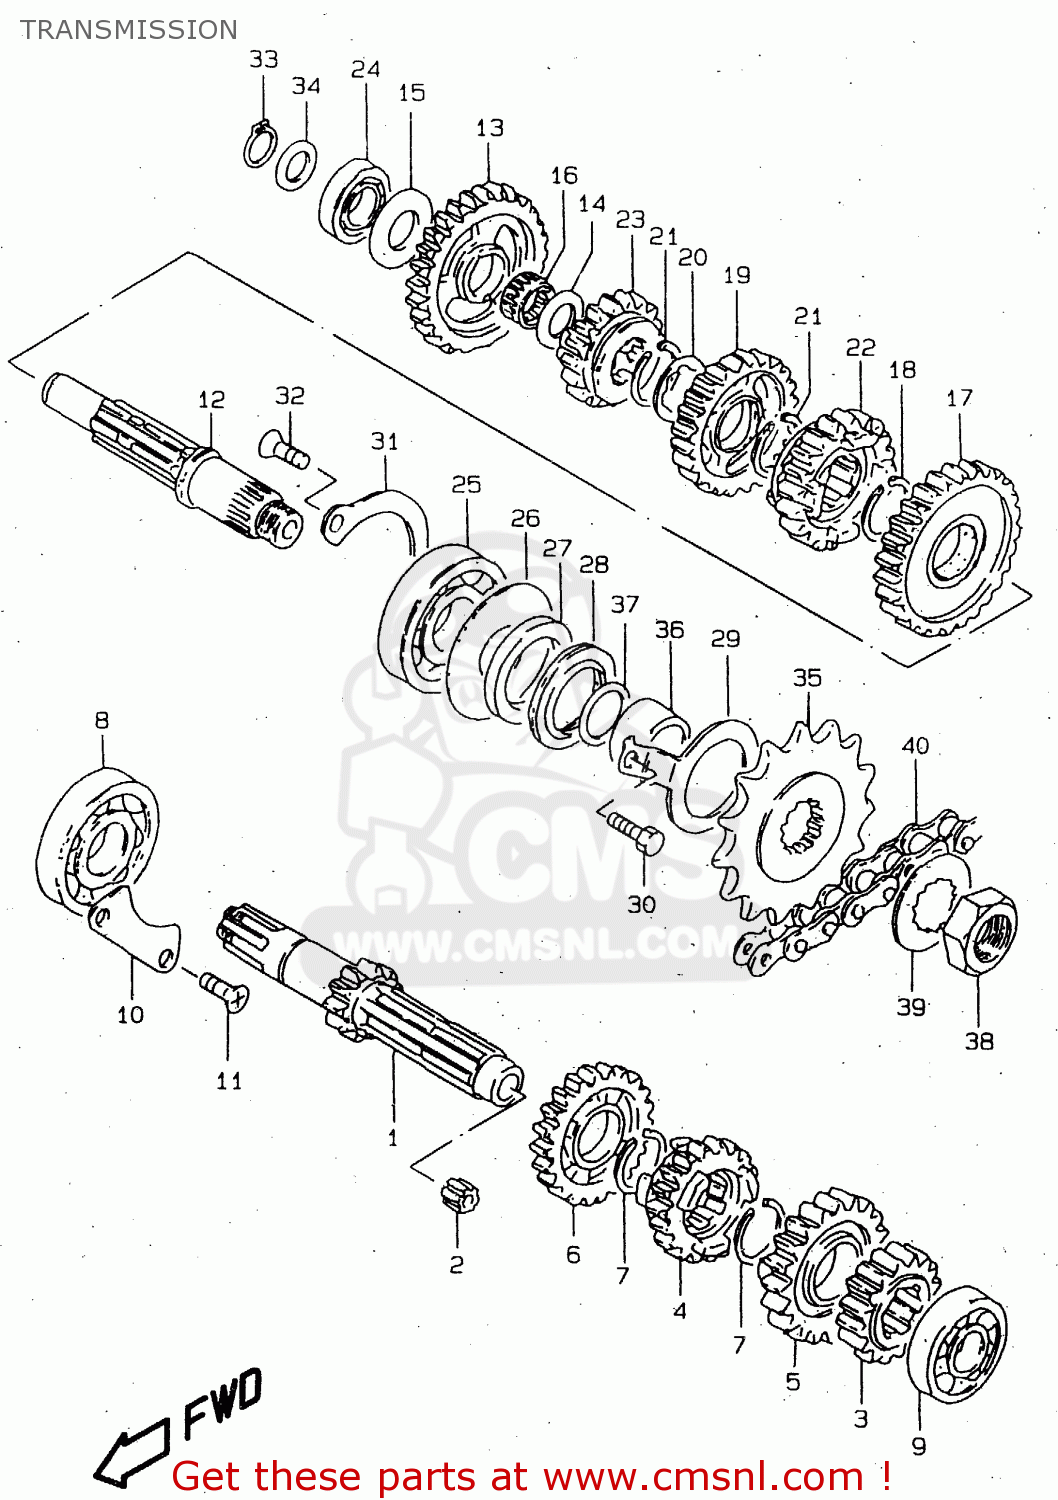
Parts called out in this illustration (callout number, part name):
1	SHAFT,COUNTER
2	BUSH
3	GEAR,2ND DRIVE(NT:16)
4	GEAR,3RD DRIVE(NT:19)
5	GEAR,FOURTH DRIVE
6	GEAR,FIFTH DRIVE (NT:22)
7	CIRCLIP
8	BEARING(22X56X16)
9	BEARING
10	RETAINER,CNTR SHAFT BEARING
11	SCREW
12	SHAFT,DRIVE
13	GEAR,1ST DRIVEN(NT:29)
14	WASHER
15	WASHER
16	BEARING(17X21X9.8)
17	GEAR,2ND DRIVEN(NT:27)
18	CIRCLIP
19	GEAR,THIRD DRIVEN
20	WASHER,LOCK
21	CIRCLIP
22	GEAR,FOURTH DRIVEN
23	GEAR,5TH DRIVEN(NT:18)
24	BEARING(17X36X12)
25	BEARING(22X56X16)
26	WASHER(35X55X1)
27	OIL SEAL (30X43X5)
28	OIL SEAL (30X43X7)
29	RETAINER,DRIVE SHAFT OIL SEAL
30	BOLT
31	RETAINER,DRIVE SHAFT BEARING
32	SCREW
33	CIRCLIP
34	WASHER
35	SPROCKET,ENGINE(NT:15)
36	SPACER
37	O RING(D:2.5,ID:21)
38	NUT
39	WASHER,LOCK
40	CHAIN(DID520VC5,100LE)
